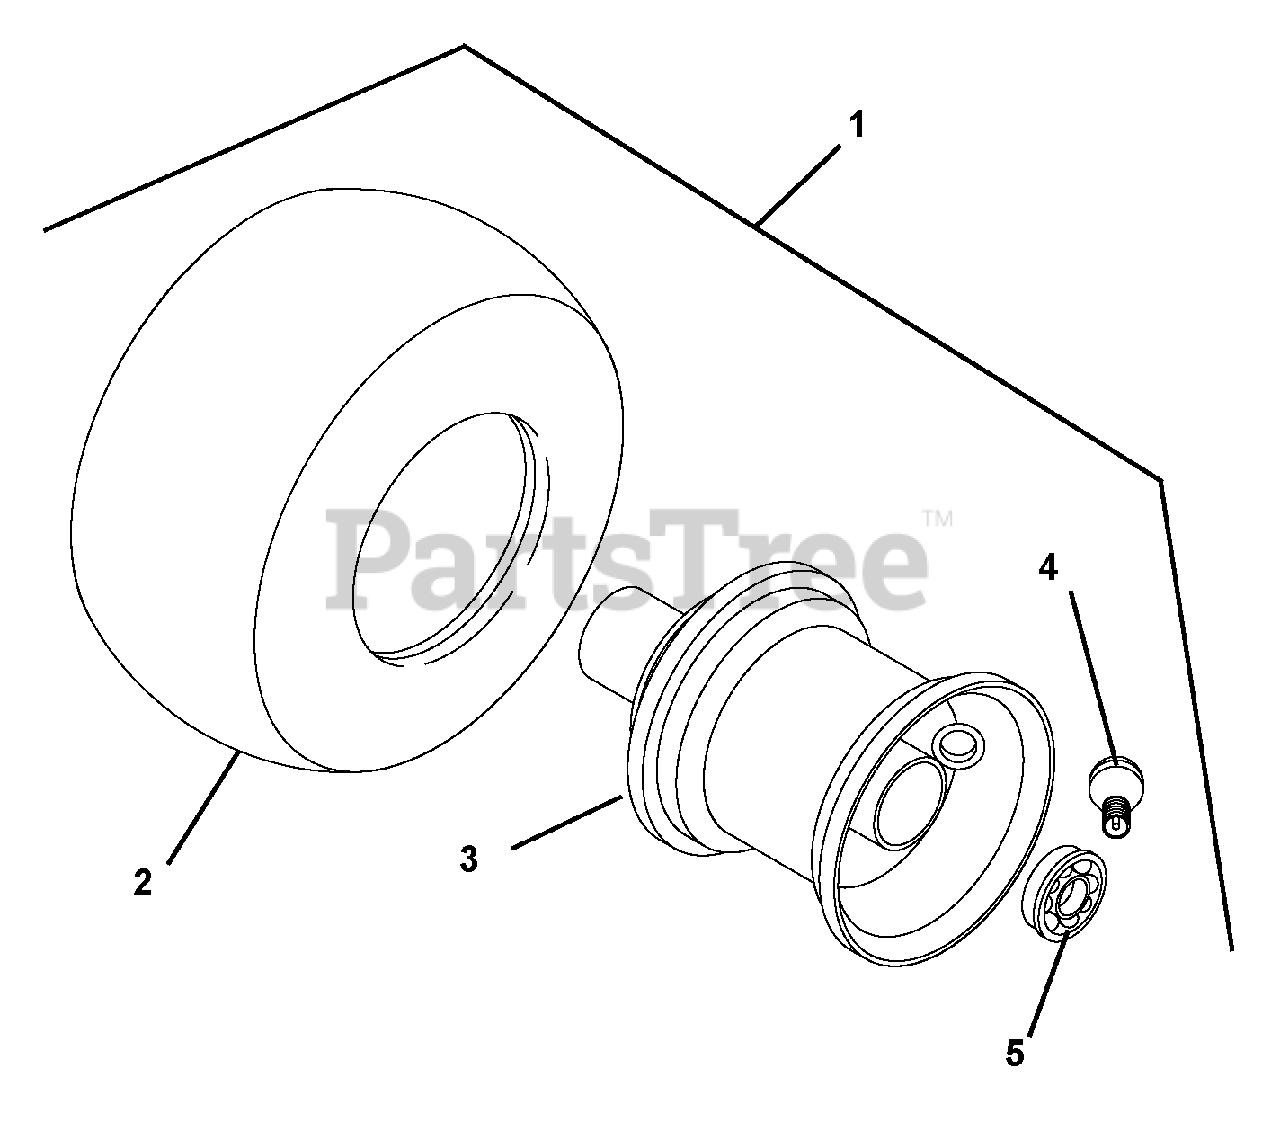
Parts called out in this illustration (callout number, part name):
1	ASSY,WHL & TIRE 16X650
2	TIRE16X650-8 4PLY RPLD 71220
3	ASSY, WHEEL
4	VALVE STEM ASS'Y
5	BEARING, 1" SEALED
